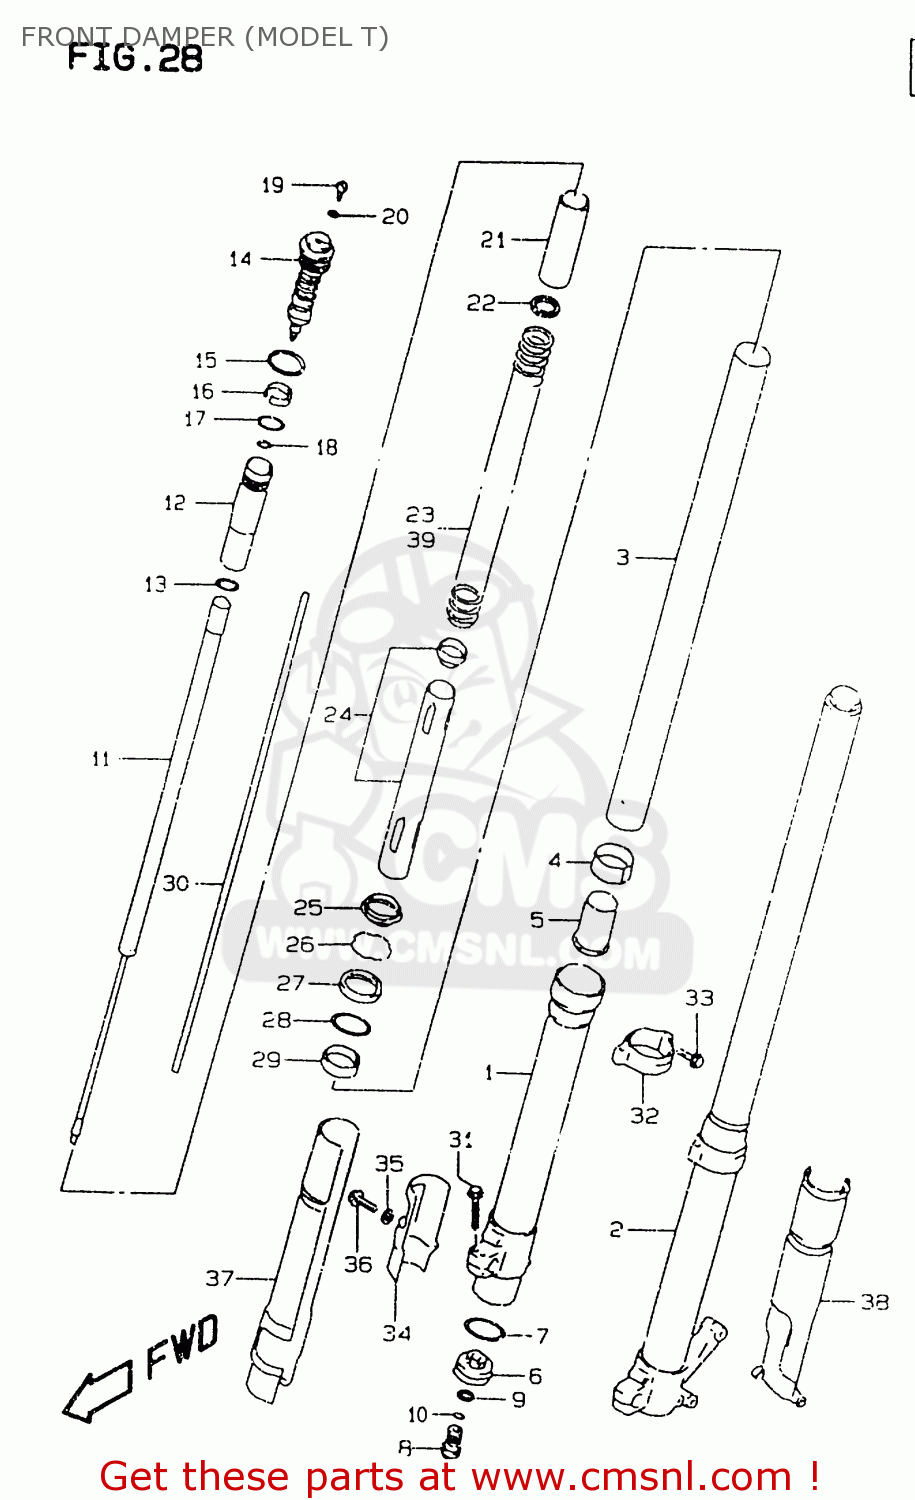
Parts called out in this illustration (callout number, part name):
1	TUBE,OUTER,R
2	TUBE,OUTER,LEFT
3	TUBE,INNER
4	BUSH,SLIDE
5	PIECE,OIL LOCK
6	PLATE,END
7	O RING
8	BOLT,CTR
9	GASKET (NAS)
10	O RING,CTR BOLT
11	DAMPER
12	TANK,SUB
13	O RING,CTR BOLT UPR
14	BOLT,FORK
15	O RING
16	BUSH,FORK BOLT SLIDE
17	O-RING,FORK BOLT,CENTER
18	O-RING,FORK BOLT,LOWER
19	BOLT,PLUG
20	O RING,PLUG
21	COLLAR,SPRING
22	JOINT,SPRING
23	SPRING,FR(K=0.40)
24	COLLAR,SPRING
25	SEAL,DUST
26	RING,STOPPER
27	SEAL,OIL
28	SPACER,SEAL
29	BUSH,GUIDE
30	ROD,PUSH
31	BOLT,HANDLE HOLDER(8X35)
32	GUIDE,FR PROTECTOR,R
33	BOLT,PROTECTOR GUIDE,6
34	PROTECTOR,OUTER TUBE,R
35	WASHER
36	BOLT
37	PROTECTOR,OUTER TUBE,R
38	PROTECTOR,OUTER TUBE,L
39	SPRING,FRONT (K=0.38)
